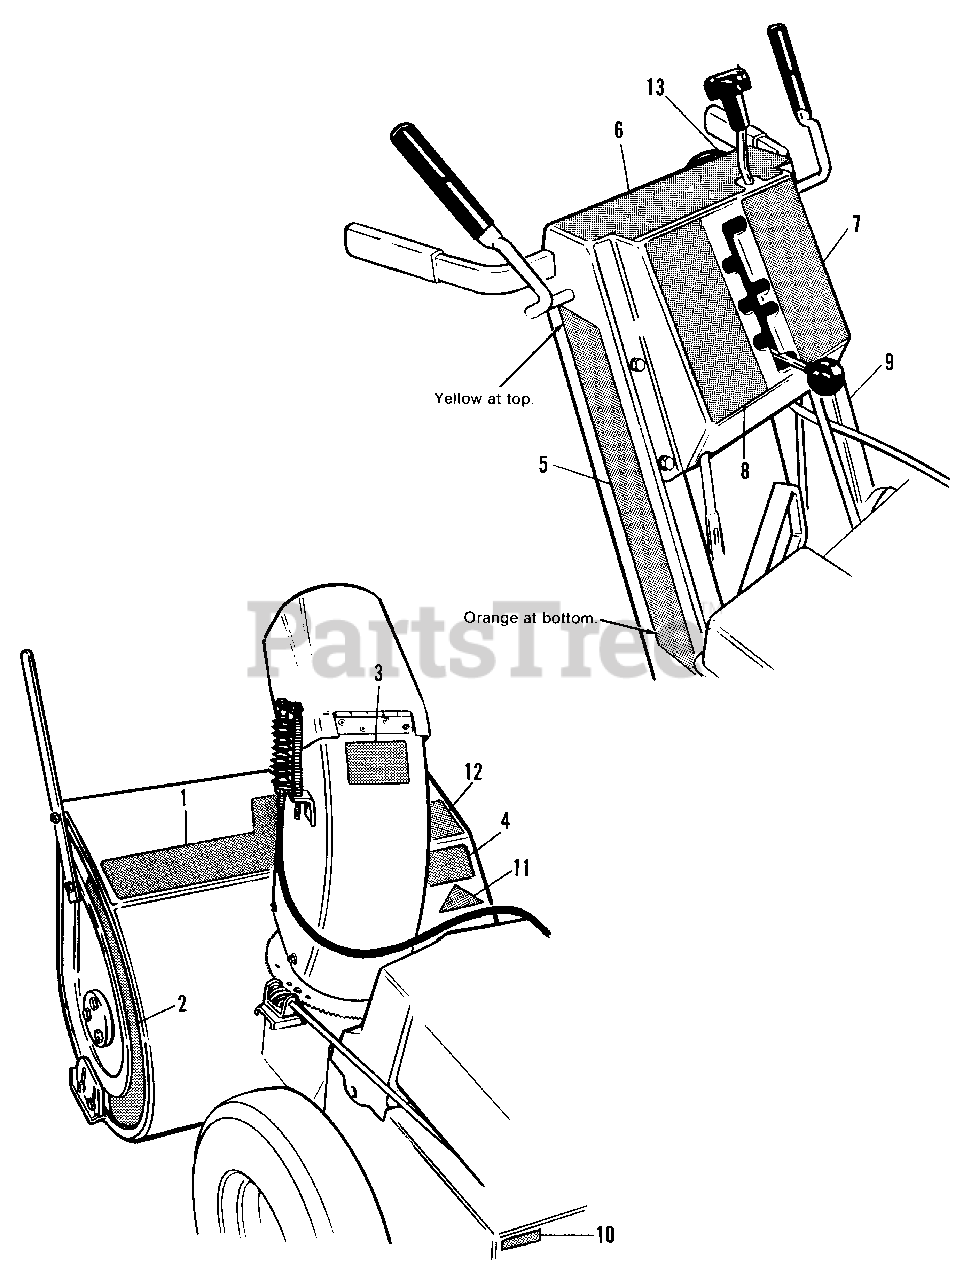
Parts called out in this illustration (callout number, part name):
1	DECAL, Housing, 560
1	DECAL, Housing, 870
2	DECAL, Housing, End L.H.
3	DECAL, Danger, Blower
4	DECAL, Hsg., End, R.H.
5	DECAL, Handle, R.H.
6	DECAL, Dash
7	DECAL, Shift Pattern, L.H.
8	DECAL, Shift Pattern, R.H.
9	DECAL, Handle, L.H.
10	I.D. Tag
11	DECAL, OPEI
12	DECAL, Danger, Auger
13	DECAL, Cable Lock
